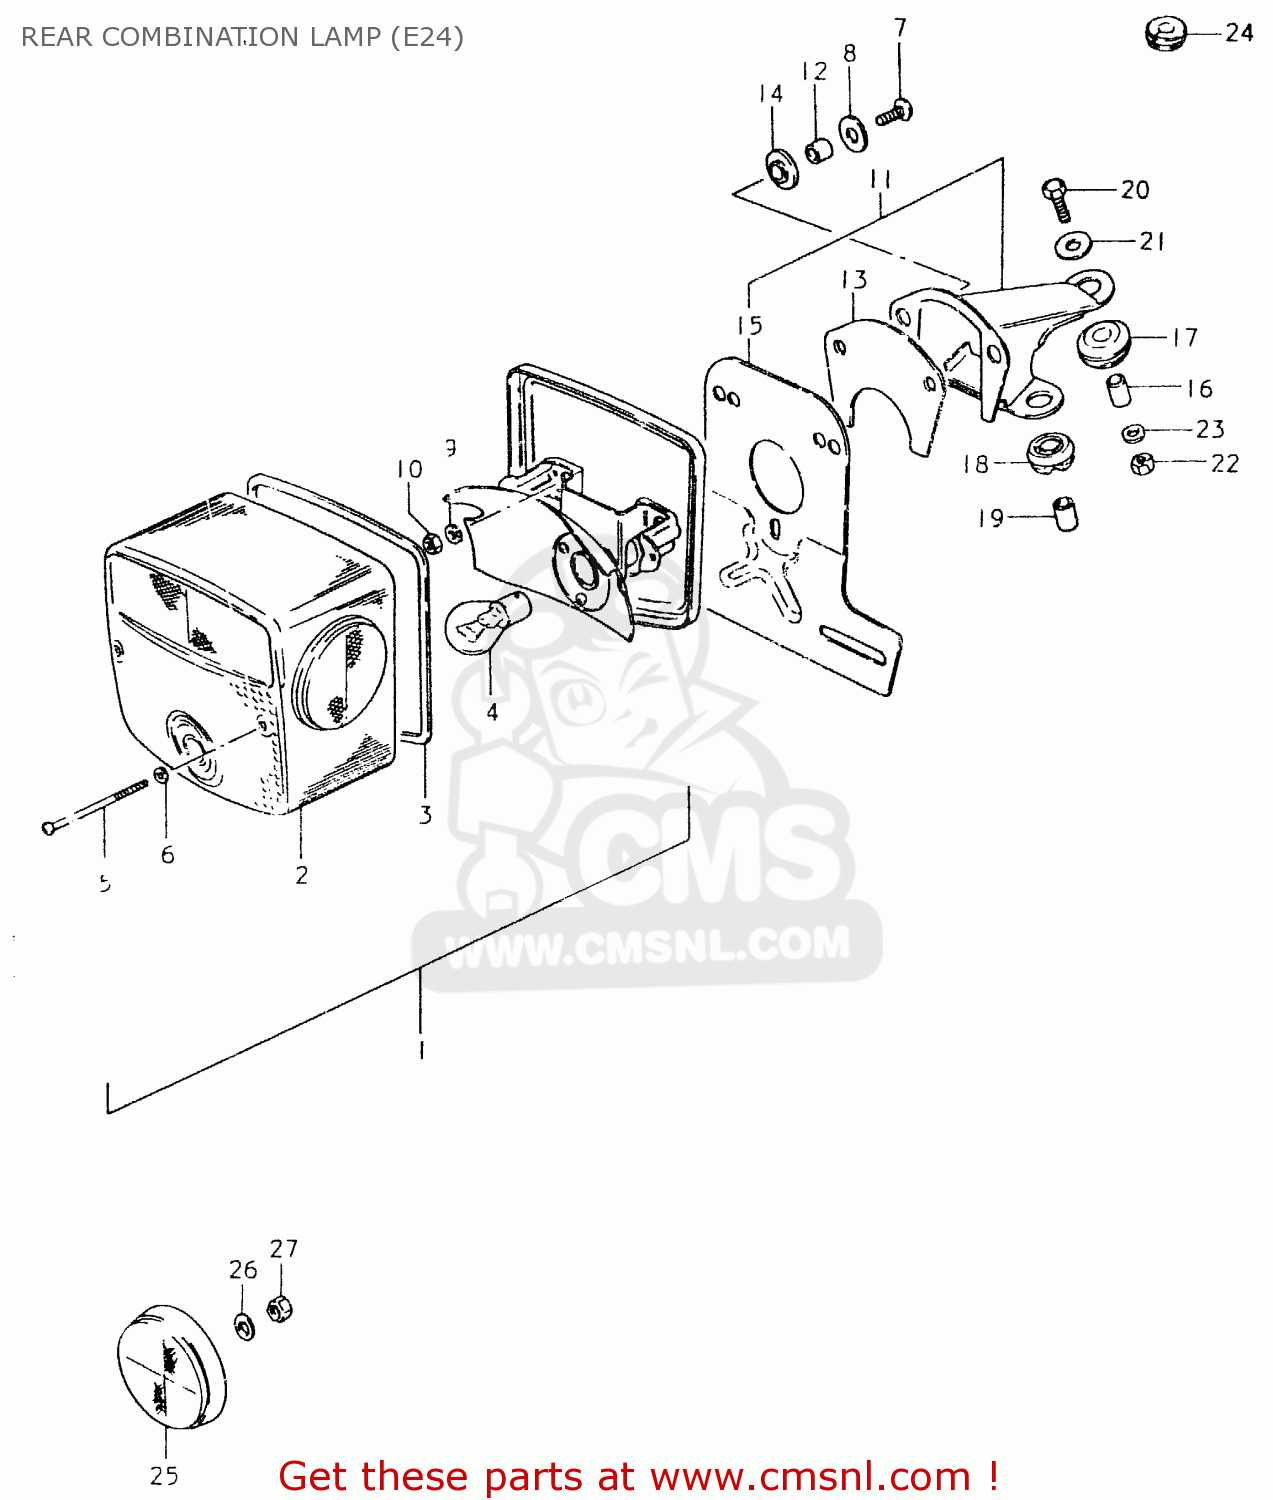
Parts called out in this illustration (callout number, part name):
1	LAMP UNIT,REAR COMBINATION
2	LENS
3	GASKET (NAS)
4	BULB(6V32/3CP,STANLEY)
5	SCREW (4X55)
6	GASKET (NAS)
7	TAPPING SCREW
8	WASHER,REAR COMBINATION LAMP
9	NUT
10	LOCK WASHER
11	BRACKET UNIT,TAIL LAMP
12	SPACER
13	CUSHION
14	CUSHION,REAR COMBINATION LAMP
15	BRACKET,LICENSE PLATE
16	SPACER
17	CUSHION,REAR COMBINATION LAMP
18	CUSHION,REAR COMBINATION LAMP
19	SPACER
20	BOLT
21	WASHER (6.5X20X1.2)
22	NUT
23	WASHER 6MM
24	GROMMET
25	REFLEX REFLECTOR,FR
26	WASHER
27	LOCK WASHER
